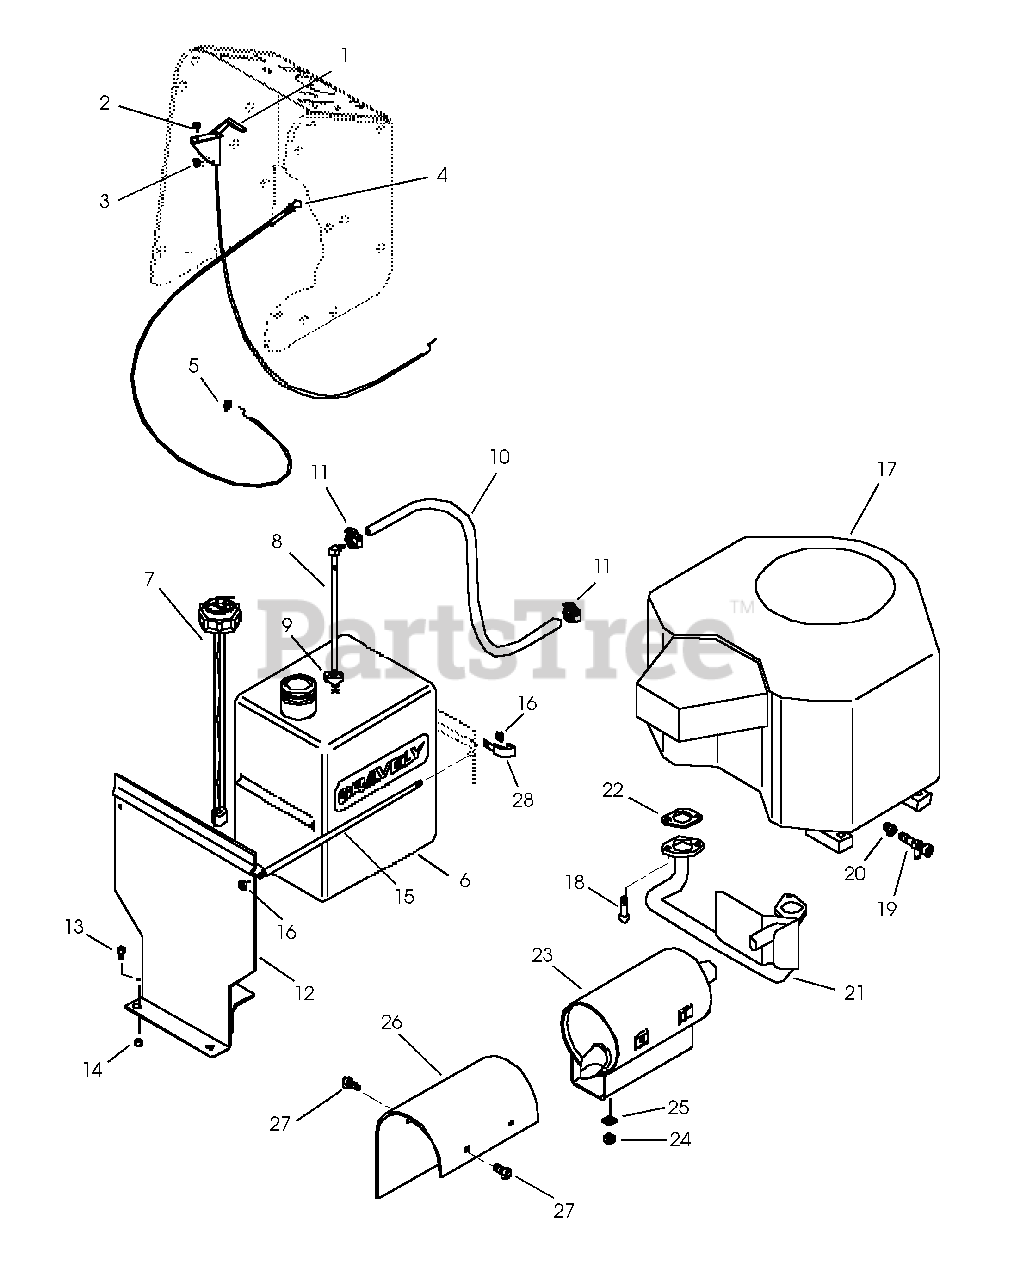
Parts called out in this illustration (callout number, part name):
1	Throttle Cable
2	Screw-Machine 10-24 x .50
3	Nut-Locking-Nylon 10-24 w/Insert
4	Control-Choke
5	Nut-Jam .375-24
6	Tank-Fuel
7	Gauge-Fuel
8	Fitting-Tank
9	Bushing
10	Gas Line Hose 1/4" x 52"
11	Hose Clamp
12	Weldment-Tank Bracket
13	Bolt-Hex .31-18 x .75 Grade 5
14	Nut-Locking-Center .31-18 Grade 2
15	Rod-Tank
16	Nut-Locking-Center .25-20
17	Engine-Kohler CV20
17	Engine-Kohler CV 25 HP
18	Screw-Socket Head M8-1.25 x 20 mm
19	Cock-Oil Drain
20	Adapter-Oil Drain
21	Manifold-Kohler CV18-25
22	Gasket-Exhaust
23	Muffler (Includes 09066300 Heat Shield)
24	Nut-Locking-Center .38-16
25	Washer-Flat-Steel .438 x 1.00 x .083
26	Heat Shield (Included with 09065600 Muffler)
27	Bolt, Hex M5 - .8 x 8 mm
28	J-Clamp
